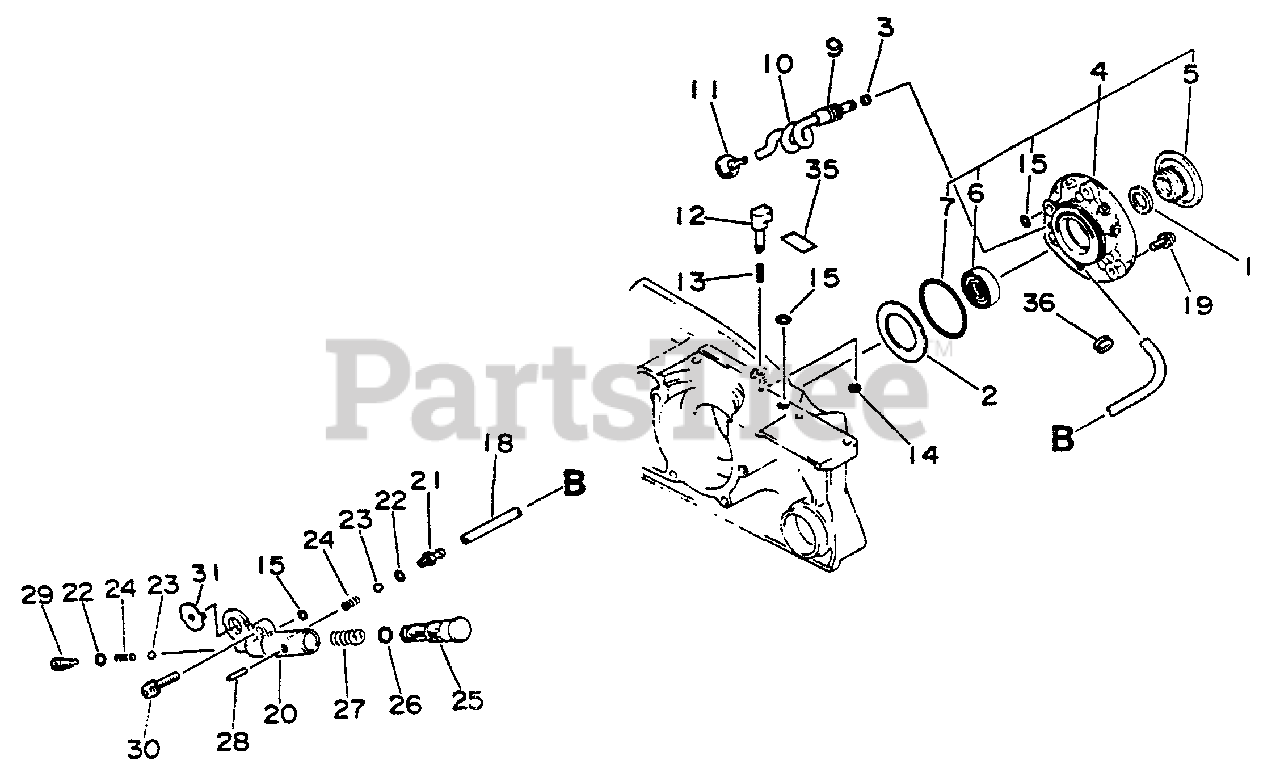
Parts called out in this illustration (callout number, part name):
2	PLATE
3	CLIP 6.6 MM
4	AUTO-OILER ASSY
5	GEAR, WORM
6	SEAL, OIL
7	O-RING
10	PIPE - SPIRAL
11	FILTER, OIL
14	RING, RETAINING - 3
15	O-RING 3
18	PIPE, OIL
19	SCREW - 4×10
20	BODY, OIL PUMP
21	CONNECTOR, PIPE
23	VALVE, BALL
24	SPRING, VALVE
25	PISTON, OIL PUMP - BLACK
26	O-RING 7 MM
28	PIN, SPRING 2×16
29	ADAPTOR, OIL PUMP
30	SCREW - 5×20
31	BRACKET, OIL PUMP
35	LABEL, CAUTION
36	CLIP 6.6 MM
